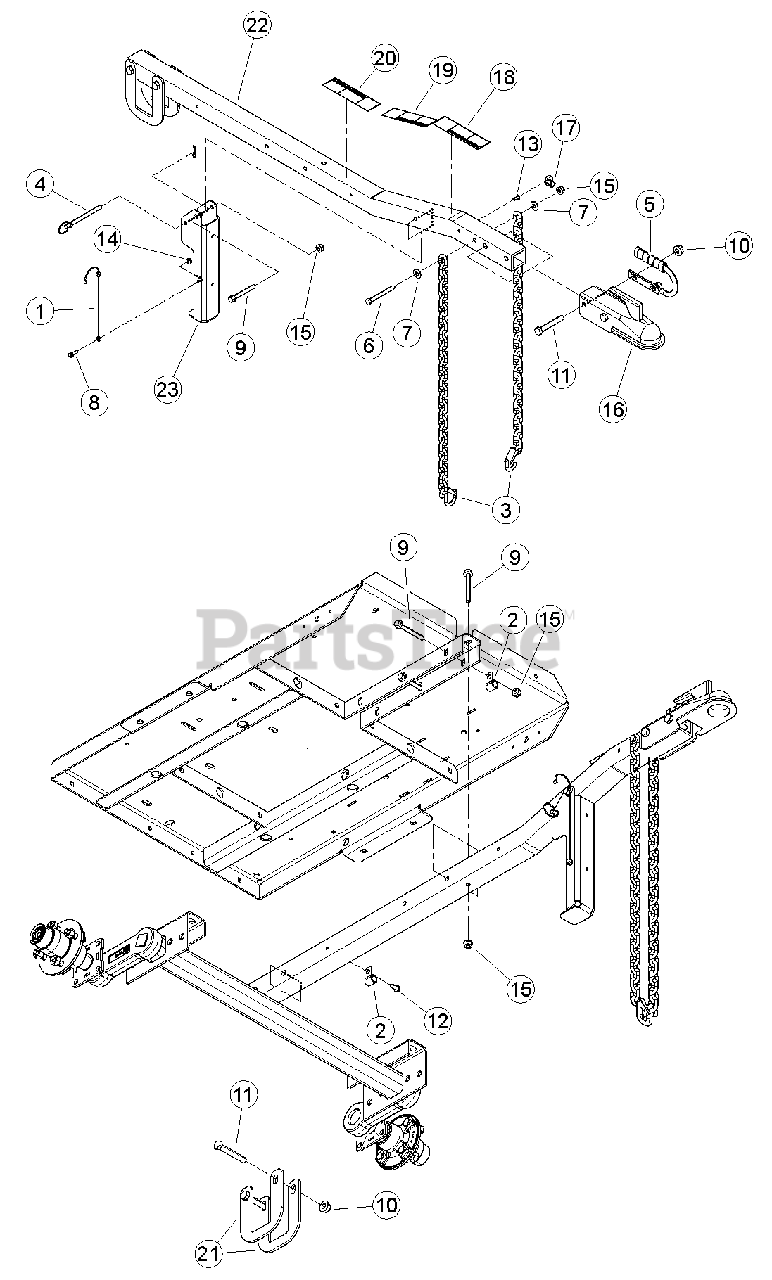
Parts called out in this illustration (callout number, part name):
1	LANYARD, NYLON
2	CLAMP, 9/16 COATED
3	CHAIN, SAFETY 5000 LB W/ LATCH
4	PIN, 3/8 HITCH
5	HANDLE, HITCH COUPLER
6	BOLT, 3/8 X 3-1/2" HEX HD GR5 ZP
7	WASHER, 3/8" FLAT ZP
8	BOLT, 1/4-20 X 3/4 HWH GR5 CZP
9	BOLT, 3/8 X 3 FLANGE NC
10	NUT, 1/2-13 NYLOCK FLANGE
11	BOLT, 1/2 X 3 1/4 HCS GR5 ZP
12	SCREW, 11/32 X 7/8 HWH AB THREAD ZP
13	RIVET, AL BLIND 1/4 X 3/4 DOME HEAD
14	NUT, 1/4-20 NYLOCK FLANGE
15	NUT, 3/8-16 NYLOCK FLANGE
16	TRAILER HITCH COUPLER
17	CLAMP, CABLE MOUNT
18	DECAL, SAFETY CHAINS
19	DECAL, TRAILER ELECTRICAL
20	DECAL, SAFE COUPLING
21	PLATE, HITCH SADDLE
22	POLE, C/S HITCH
23	WELDMENT, STAND JACK
